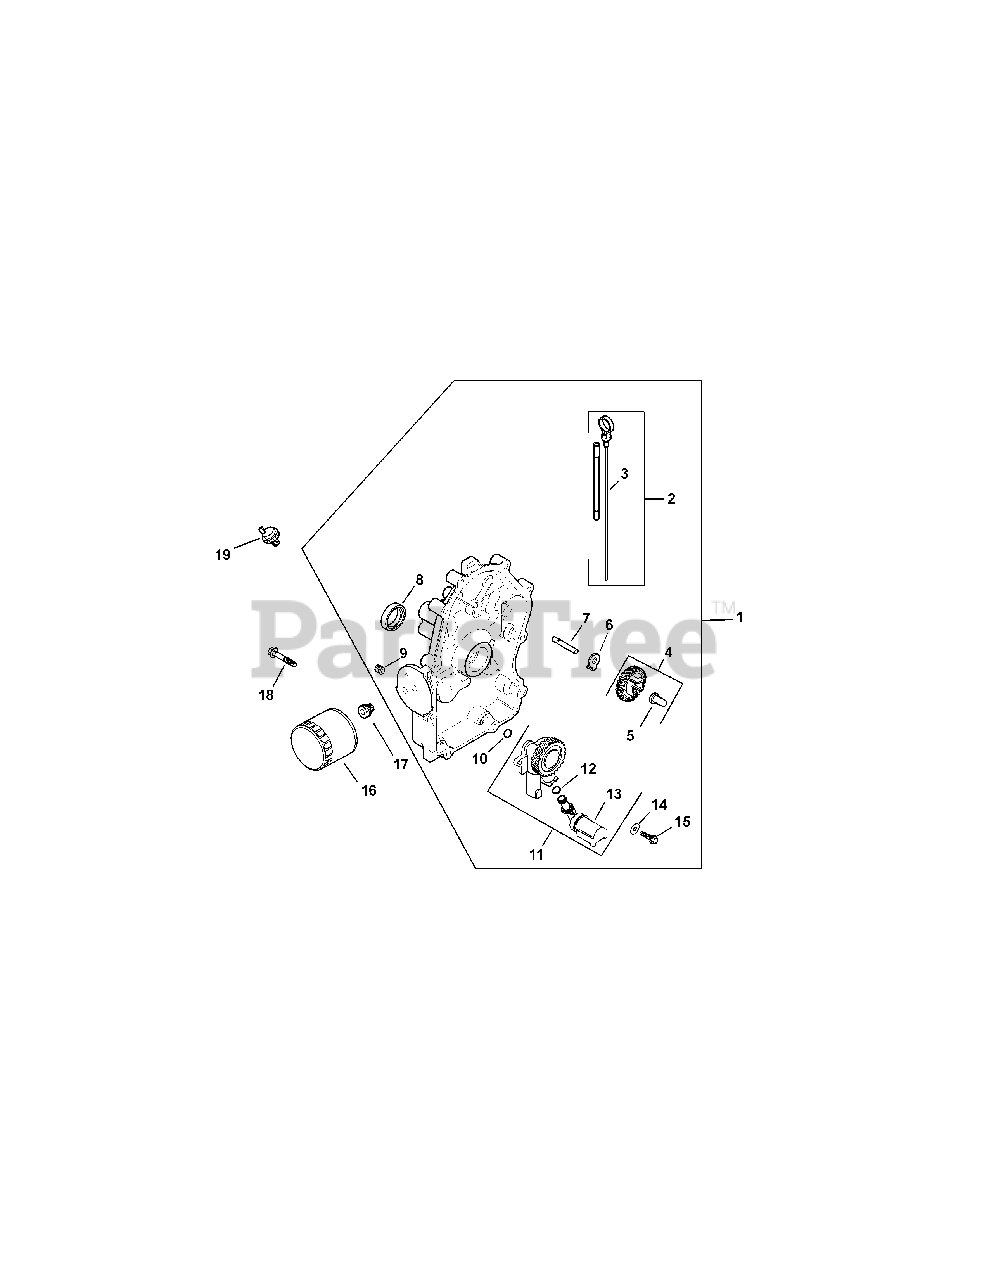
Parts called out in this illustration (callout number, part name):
1	Closure Plate Assembly
2	Kit, Dipstick/ Tubes (Includes 3)
4	Kit, Governor Gear w/Pin (Incl 5)
5	Pin, Governor Regulating
7	Shaft, Governor Gear
9	Plug, Ctsk Pipe, 1/8"
11	Kit, Oil Pump Ass’y (Incl 12, 13)
12	O-Ring, Oil Pick-up
13	Pick-up, Oil
14	Washer, Flat 6 mm
15	Screw, Flg Thd Frm M6x1.0x25
17	Nipple, Oil FIlter
18	Screw, Flg M8 x 1.25 x 45
19	Switch, Oil Pressure
